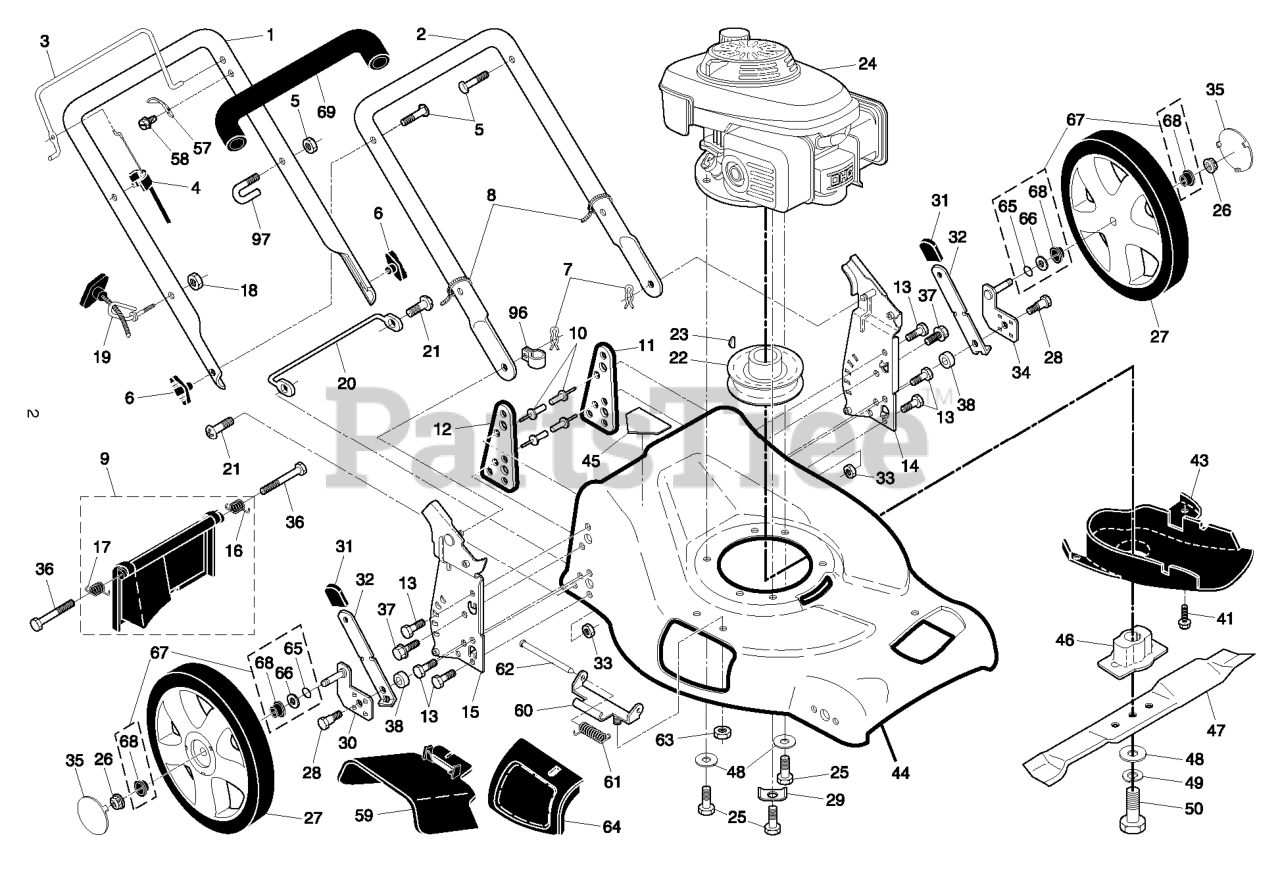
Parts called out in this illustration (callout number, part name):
2	LOWER HANDLE
3	BAIL, FLAT AUTO WALK
4	CABLE.ENGINE BRAKE.MZR
5	BOLT, HANDLE 5/16-18X1.75
6	HNDL.KNOB.GRAY
7	HAIRPIN COTTER
8	TIE GUIDE
9	KIT.DOOR.RR.ASM.21.FWGD
10	RIVET BLIND
11	SUPPORT BRACKET LH
12	SUPPORT BRACKET RH
13	SCREW 14-20 X 5/8
14	BRKT.ASM.HNDL.21FGD
15	BRKT.ASM.HNDL.21FGD.EZ
17	SPRING.REAR.DOOR.EZ.21
18	NUT
19	ROPE, GUIDE
22	ENGINE PULLEY
23	HI-PRO KEY
25	BOLT 3/8-16X1-1/8
26	HEX FLANGE LOCKNT
27	RP WHEEL 14X2
28	SHOULDER BOLT
29	WASHER.ENGINE.BZP
30	AXLE ARM ASSEMBLY RR
31	KNOB, DEFLECTOR
32	SELECTOR SPRING
33	NUT.71038.31-18.HEX.NYLOCK
34	AXLE ARM ASSEMBLY LR
35	HUBCAP
37	SELF-TAPPING SCREW 5/16-18X3/4
38	WASHER.FLAT.34X1.38X22
41	SCREW.HEX.WSH
43	DEBRIS.SHIELD.FWGD.WALK.MOWER
45	DECAL.INTERNATIONL.CUTFINGER
46	BLADE ADAPTER
47	21" PUSH BLADE
48	WASHER,HARDEN
49	LOCKWASHER
50	SCREW, HEX HD 3/8-24 X 1-3/8
57	BRACKET UPSTOP
59	DEFLECTOR.CLIPPIN.21.FGD
60	BRACKET.ASM.HINGE.21.FWGD.
61	SPRING
62	ROD.HINGE.21
63	LOCKNUT.NYLOC.1/4-20
64	DOOR.MULCH.21.REAR.FWGD
65	O-RING
66	WASHER.FLAT.1/2
67	KIT.BUSHING.WHEEL.14"
68	Bushing, Nylon, Black
69	GRIP.HANDLE.FOAM.WIDE.(1 SIDE)
96	CLIP.CABLE.BLK
